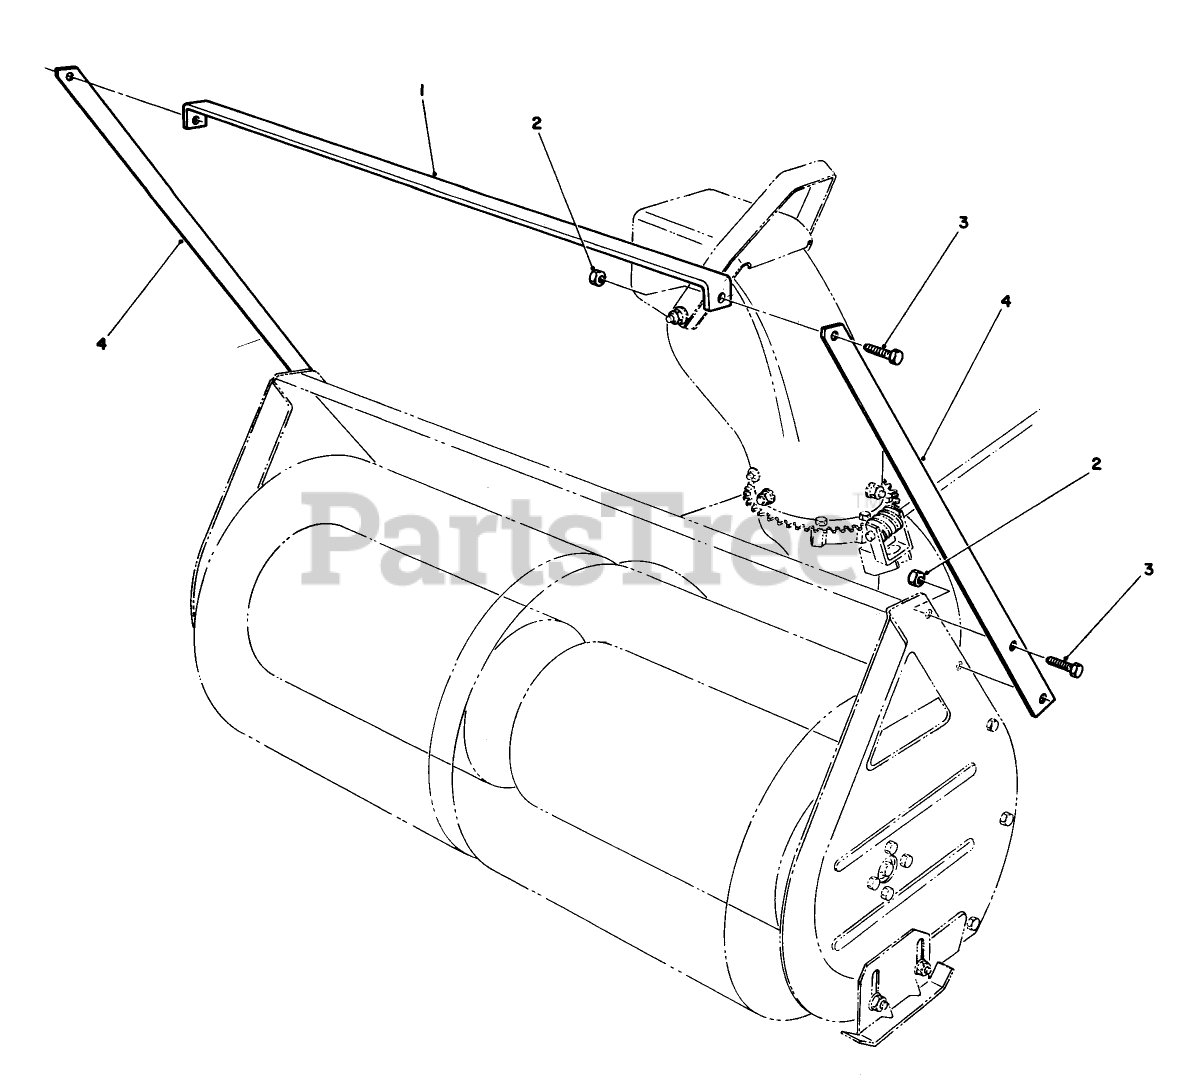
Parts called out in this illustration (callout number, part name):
1	32 TOP DRIFT BREAKER
2	NUT-LOCK, CONE
3	SCREW-HH
4	SIDE DRIFT BREAKER
